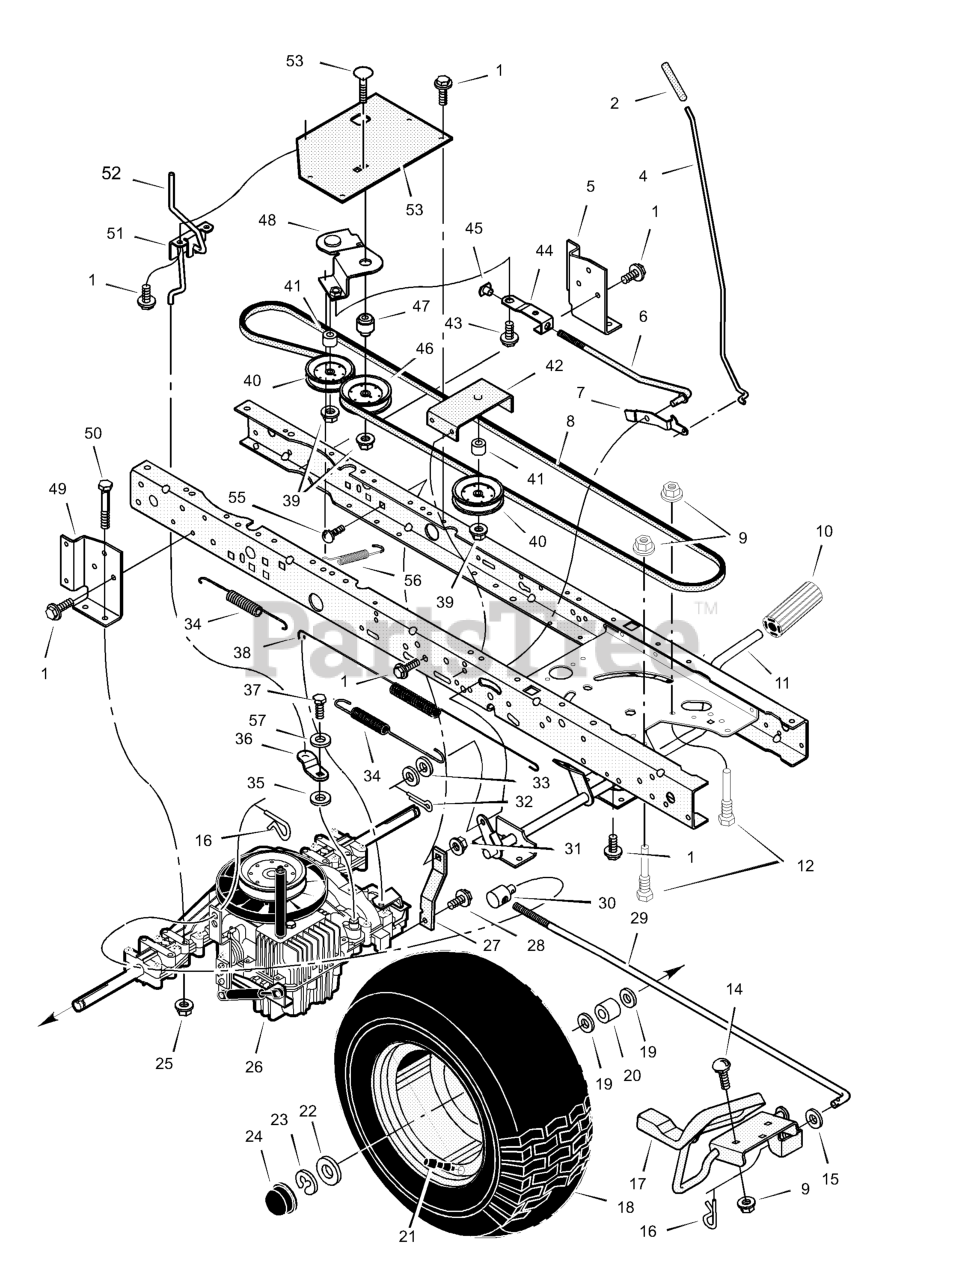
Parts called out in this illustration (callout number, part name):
2	Grip, Parking Brake
4	Rod, Parking Brake
5	Bracket, Transaxle - Left
6	Rod, Clutch
7	Latch, Parking Brake
8	V-Belt, Drive
9	Nut, Flange
10	Pedal, Brake/Clutch
11	Assembly, Brake Pedal
12	Screw, Guide
14	Bolt, Carriage
16	Pin, Hair
17	Pedal Assembly, Hydro
18	Wheel & Tire Ass'y - Rear 20"
20	Spacer
21	Stem, Valve
24	Cap, Hub
25	Nut, Centerlock
26	Transaxle **
27	Strap, Torque
29	Rod, Control
30	NUT, Adjusting, 1/2-13
31	Nut, Centerlock
32	Pin, Cotter
34	Spring, Extension
36	ARM, Disconnect
37	Capscrew
38	Spring, Brake
39	Locknut, Flange
40	Pulley, Idler
42	Bracket, Idler Assembly
43	Bolt, Shoulder
44	Link, Clutch
45	Nut, Tee
46	Pulley, Idler
47	Bushing, Pivot
48	Arm Assembly, Idler
49	Bracket, Transaxle -Right
50	Bolt, Hex
51	Bracket, Disconnect
52	Rod, Disconnect
53	Bracket, Idler Pivot
54	Bolt, Carriage
55	Bolt, Carriage
56	Spring, Clutch
